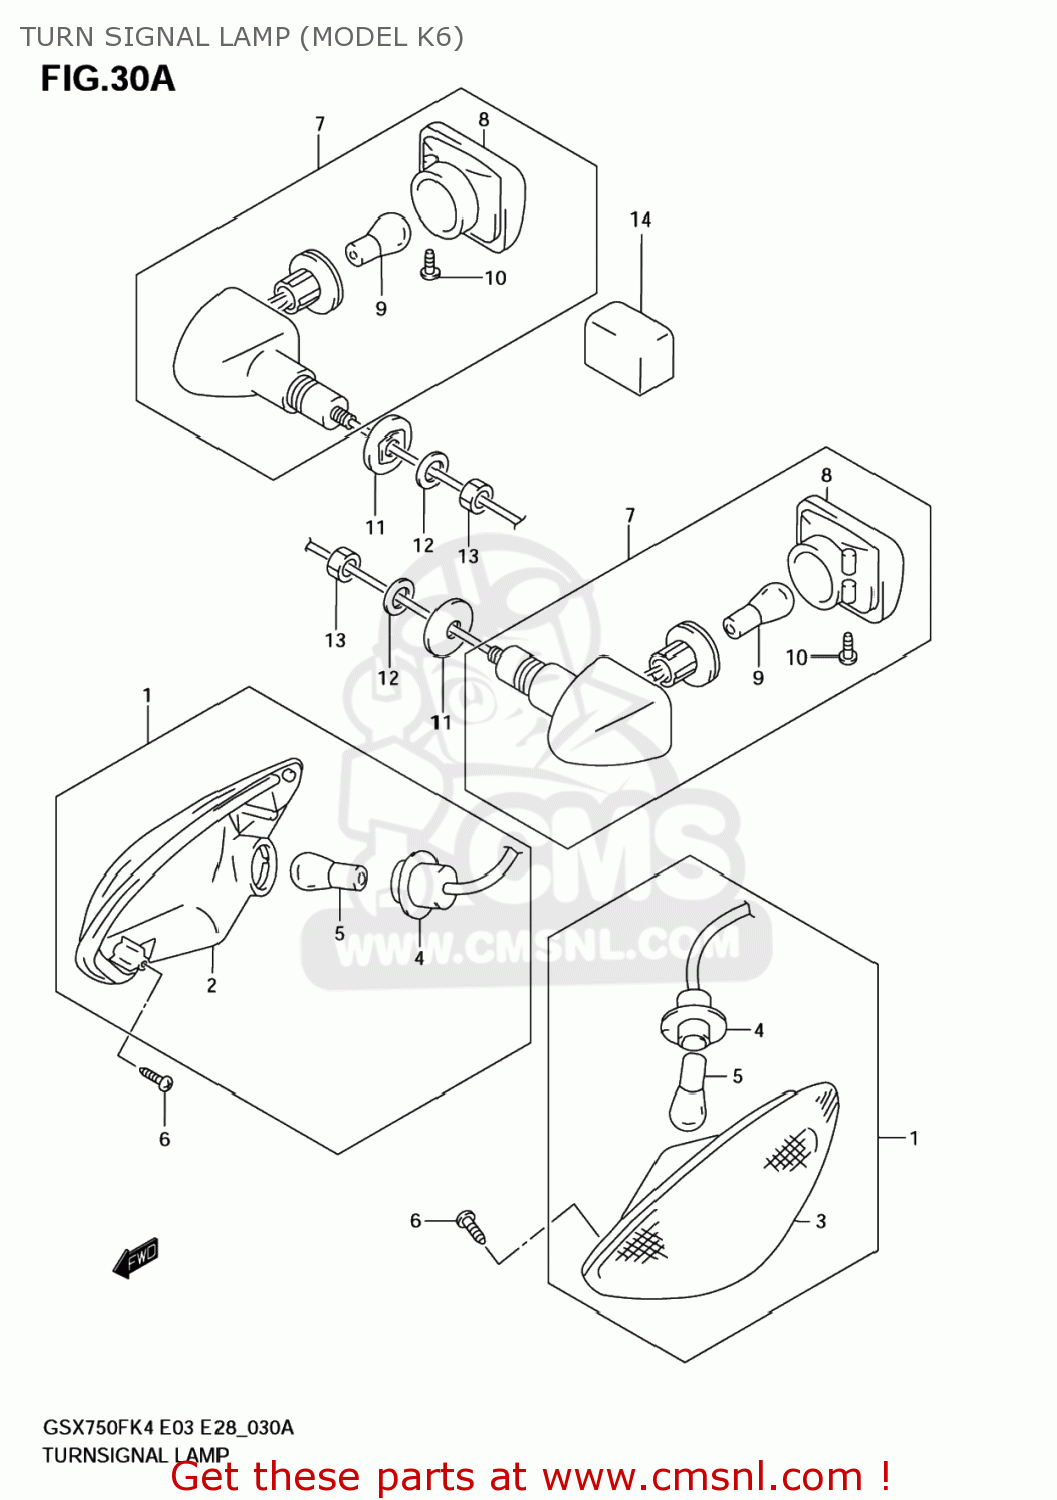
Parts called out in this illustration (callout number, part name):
1	LAMP ASSY,FR TURN SIGNAL,R
2	LAMP UNIT,R
3	LAMP UNIT,L
4	SOCKET & CORD,R
5	BULB(12V21W,AMBER)
6	SCREW
7	LAMP ASSY,RR TURNSIGNAL,R
8	LAMP UNIT
9	BULB(12V21W,AMBER)
10	SCREW
11	SPACER,RR TURNSIGNAL
12	WASHER(10.5X30X2.3)
13	NUT
14	RELAY ASSY,TURNSIGNAL LAMP
